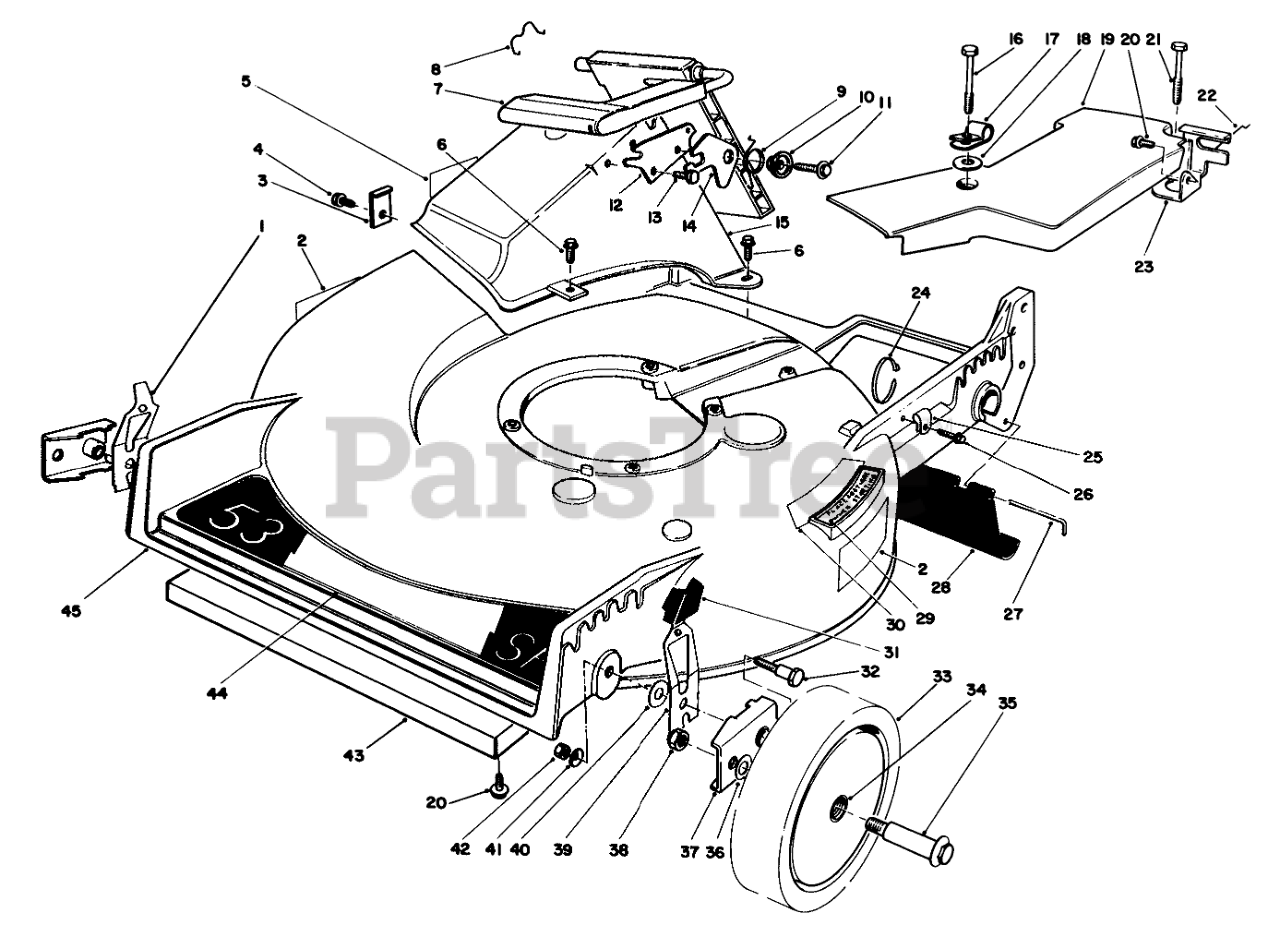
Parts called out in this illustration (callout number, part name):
1	R HP SPRING ARM ASM
2	Decal Danger
3	TUNNEL CLIP
4	SCREW
5	DECAL - DANGER
6	SCREW-HWH
7	Discharge Door Assembly
8	DOOR RET SPRING
9	TORSION SPRING
10	DOOR SPACER
11	SCREW-HWH
12	DOOR LATCH PLATE
13	SCREW-PLASTITE
14	SAFETY LATCH
15	Tunnel Discharge
16	SCREW-SPECIAL
17	CLAMP-CABLE
18	WASHER
19	Cover-Belt
20	SCREW-HWHTF
21	SCREW-HHFTF
22	RETAINER-CABLE
23	Bracket-Traction Adj.
24	TIE-CABLE
25	CLAMP-CABLE
26	SCREW
27	ROD-SHIELD
28	SHIELD-TRAILING
29	DECAL - STEP PAD INT'L
30	Decal-Place Foot Here
31	KNOB-ARM
32	PIVOT SCREW
33	Wheel & Tire Assembly (Incl. Ref. #34)
34	BUSHING
35	WHEEL BOLT
36	WASHER
37	HP PIVOT ARM ASM
38	Nut
39	L. HP SPRING ARM ASM
40	WASHER-PIVOT
41	WASHER-BELLEVILLE
42	NUT-LOCK, NI
43	Shield-front
44	DECAL - 53 SP DECK
45	21" Housing
